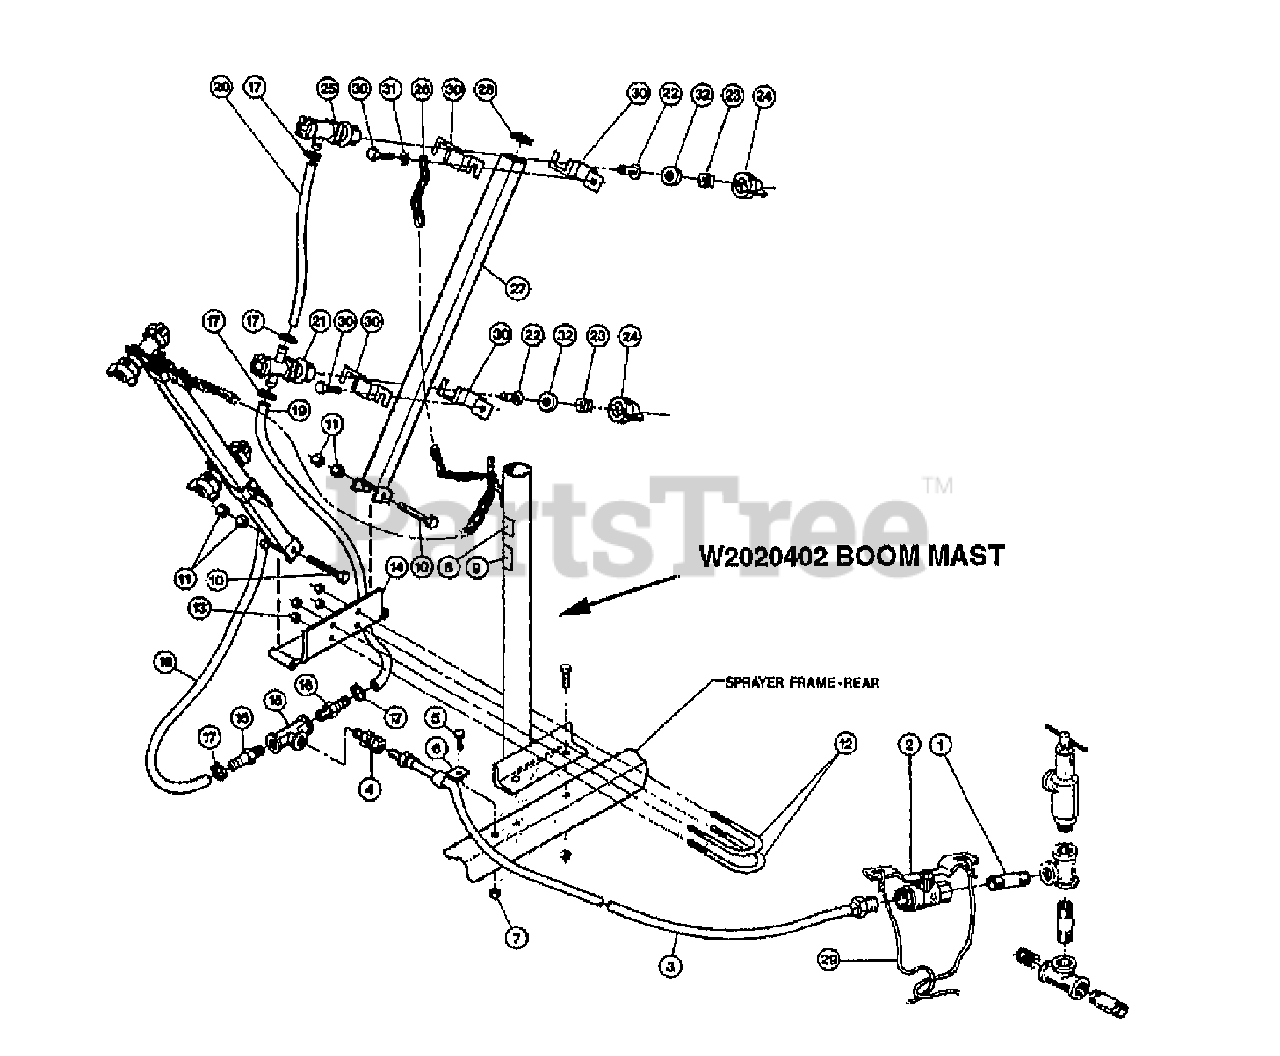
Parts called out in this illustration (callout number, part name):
1	NIPPLE-PIPE 50X2 GALVANIZED
2	VALVE-BALL .5 WING HANDLE
3	ASSM-44" HOSE W/CLAMPS W207566
4	ADAPTER-.25FPT X .25NPT
5	SCR-SLOT.H.10-24X2
6	CLAMP-HOSE NYLON
7	SCR-PHS M10-24X.75 ZP
8	DECAL-DANGER AVOID W2045146
9	DECAL-40PSI CAUTION W2045147
10	OBS SCR HH 5/16-18X2.5
11	NUT-HEX 5/16-18 ZP
12	BOLT-U .25 X 1.75 X 3
13	NUT-HEX 1/4-20 ZP
14	ASSM-BOOM SWVL PLATE
15	TEE-PIPE .25FPT BRASS
16	SHANK-HOSE .375 X .25NPT
17	CLAMP-HOSE 10829
18	HOSE-VINYL 7.5" 300PSI
19	HOSE-VINYL 11.5" 300PSI
20	HOSE-VINYL 18" 300PSI
21	NOZZLE BODY W/2HOSE SHANK
22	STRAINER-NYLON W8079PP
23	NOZZLE-BRASS SPRAY BOOM
24	CAP-NOZZLE (BOOM ATTCH)
25	NOZZLE BODY SINGLE SHANK
26	CHAIN-DOUBLE LOOP W2020104B
27	ASSM-BOOM TUBE
28	PLG-SQ 16GA TUBE OLD W9565K23
29	ROPE-.25 X 10'
30	ASSM-CLAMP & SCR
31	WASHER-.75X.312X.065 ZP
32	GASKET-NOZZLE SEAT
